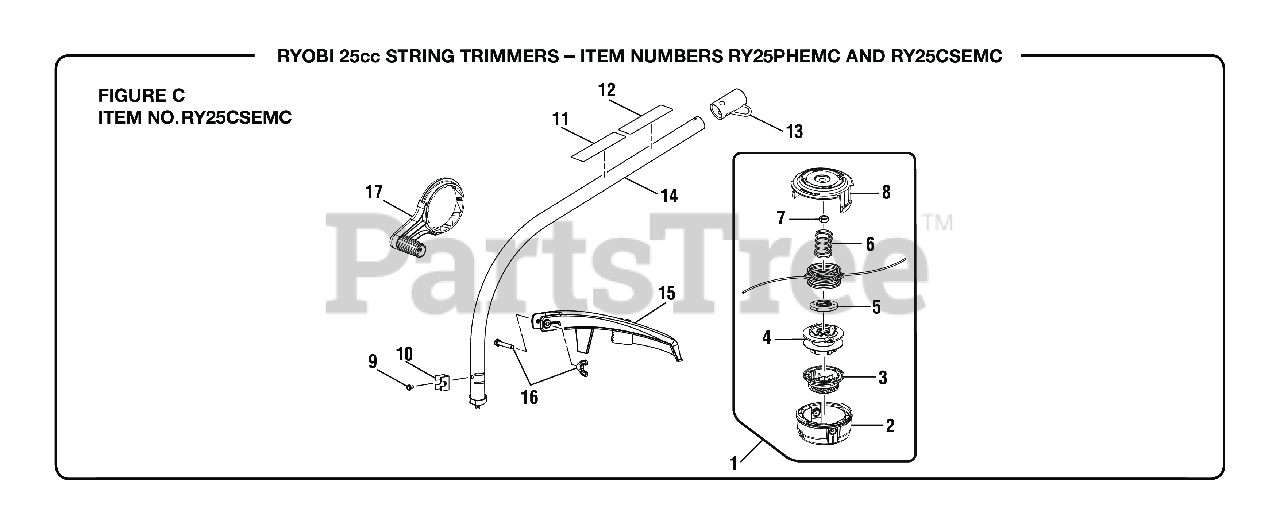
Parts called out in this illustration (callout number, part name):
1	Trimmer Head Assembly (.095)
2	Lower Housing
3	Bump Knob (Green)
4	Spool Assembly
5	String Guide
6	Compression Spring
7	Hex Nut (M8)
8	Upper Housing
9	Screw (#10-32 x 3/8 in., Hex Washer Hd. S.T.)
11	Ryobi EXPAND-IT Label
12	Warning Icon Label
13	Storage Hanger Cap
14	Curved Shaft Assembly
15	Grass Deflector Assembly
16	Fastener Parts Kit
17	Crank Handle Assembly
